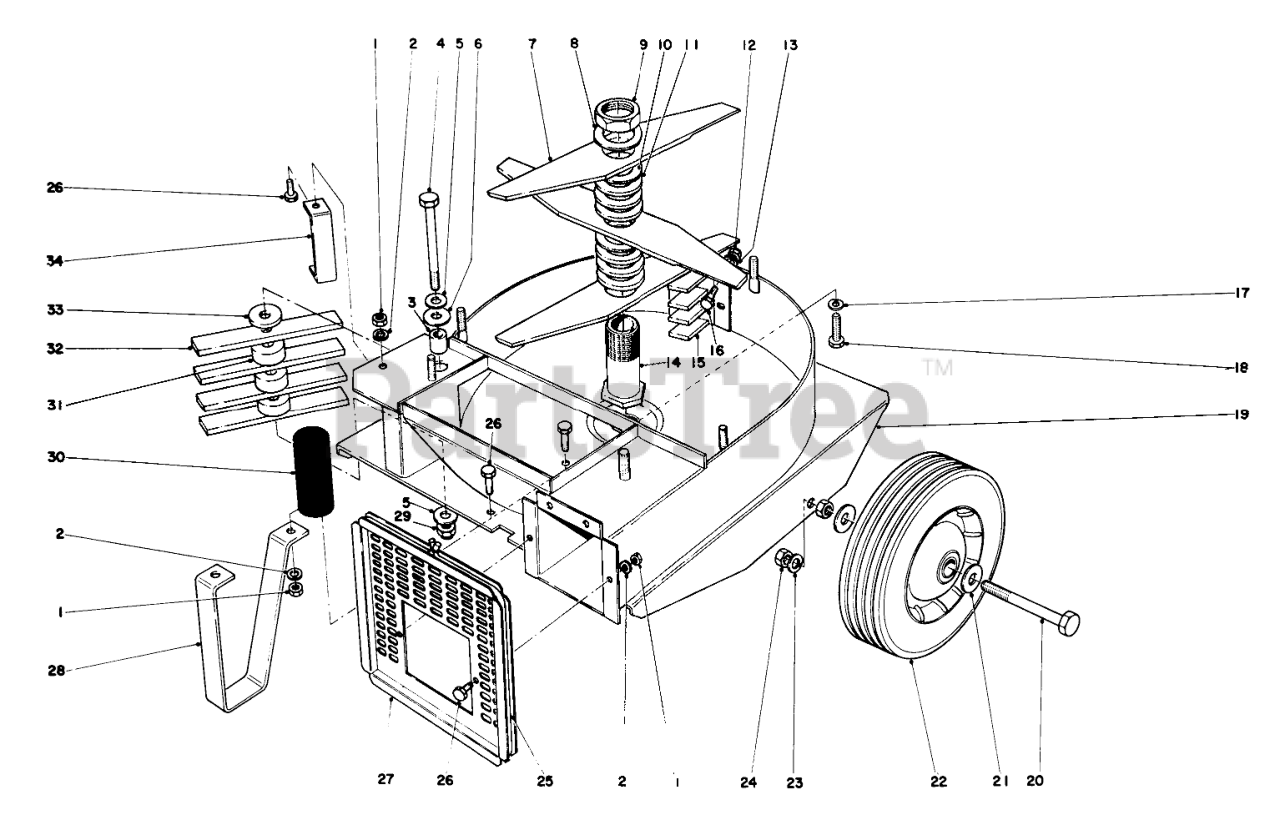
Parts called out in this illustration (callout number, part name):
1	NUT-HEX
2	WASHER-LOCK
3	Sleeve
5	Washer
6	Washer
7	Blade
8	Washer
10	Thin spacer
11	Thick spacer
12	NUT-HEX
13	WASHER-LOCK
14	Rotor hub
15	Secondary plate
16	SCREW-HH
17	WASHER-LOCK
18	SCREW-HH
20	SCREW-HH
21	WASHER-FLAT
22	Wheel & tire
23	WASHER-LOCK
24	NUT-HH
25	Bag cord
26	SCREW-HH
27	Bag plate
28	Leg stand
29	NUT-HEX
30	Rubber shock
31	Spacer, thick
32	Finger shredder
33	Thin spacer
34	Finger backstop
